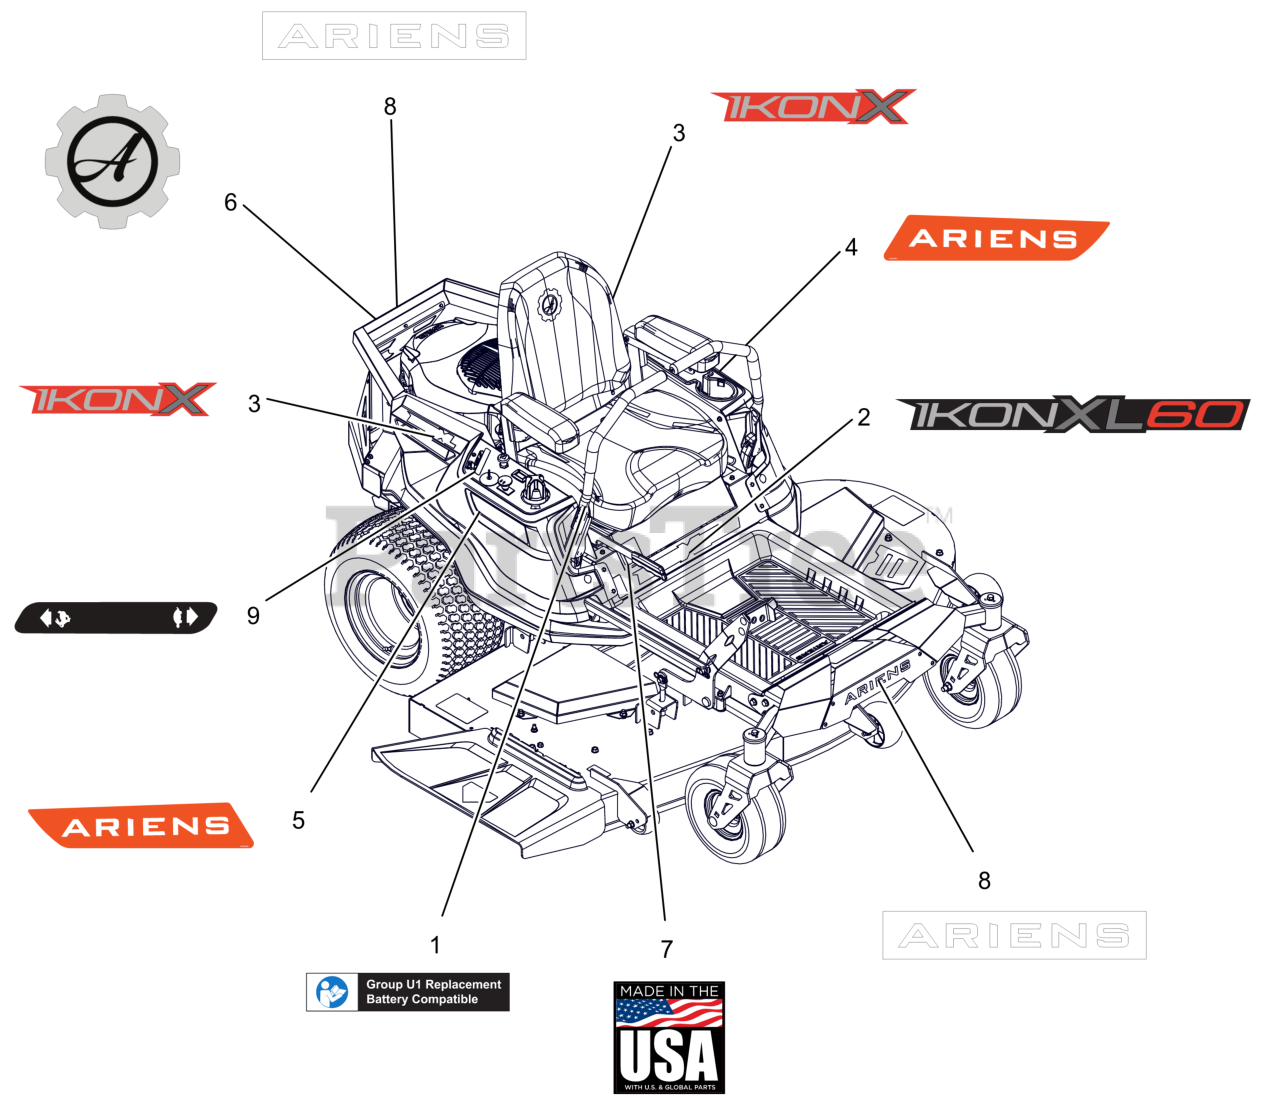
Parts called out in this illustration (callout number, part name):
1	DECAL, U1 BATTERY REPLACEMENT
2	DECAL, IKON-XL 60"
3	DECAL, IKON-XL
4	DECAL, FENDER LH
5	DECAL, FENDER RH
6	DECAL, ARIENS-GEAR BADGE -THK
7	DECAL, MADE IN USA
8	DECAL - ARIENS 9.625"
9	DECAL, DASH DECAL
